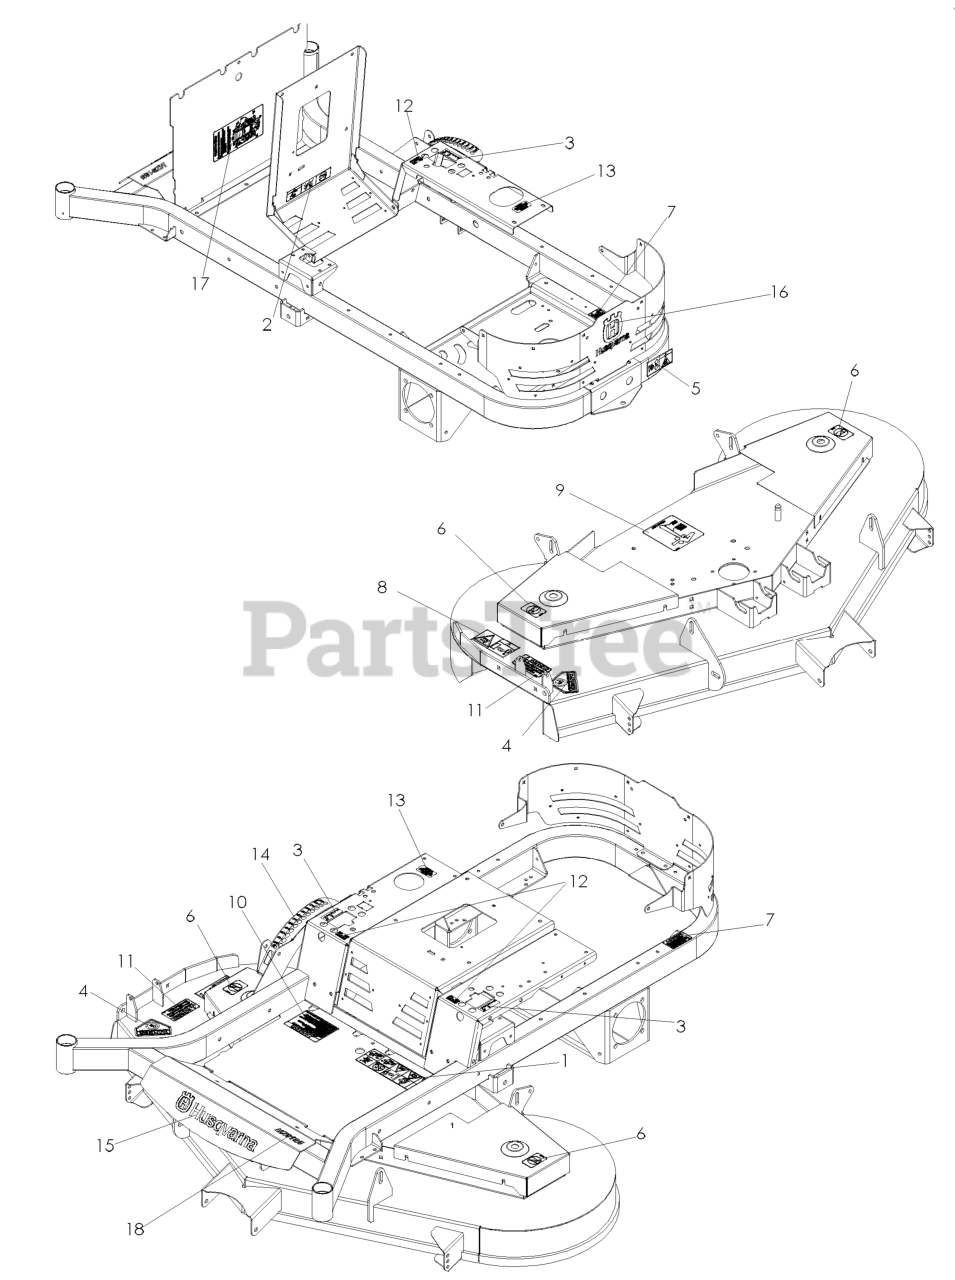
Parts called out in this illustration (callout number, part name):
1	DECAL, WARNING
2	EURO DECAL-BATTERY WARNIN6
3	DECAL, MOTION CONTROL
4	DECAL, CPSC
5	DECAL, BELT DRIVE
6	DECAL, NO STEP
7	DECAL, PROP. 65
8	DECAL, EURO SEVERING
9	RP DECAL, BELT ROUTING
10	DECAL, WARNING
11	DECAL, CAUTION
12	DECAL, F.S.T.
13	DECAL, OIL TANK
14	DECAL, HEIGHT ADJUST
15	DECAL, HUSQ 12" BLUE
16	DECAL, CROWN H BLUE
17	DECAL, SERVICE
18	DECAL, MZ5225
18	DECAL, MZ6125
18	DECAL, MZ7227
